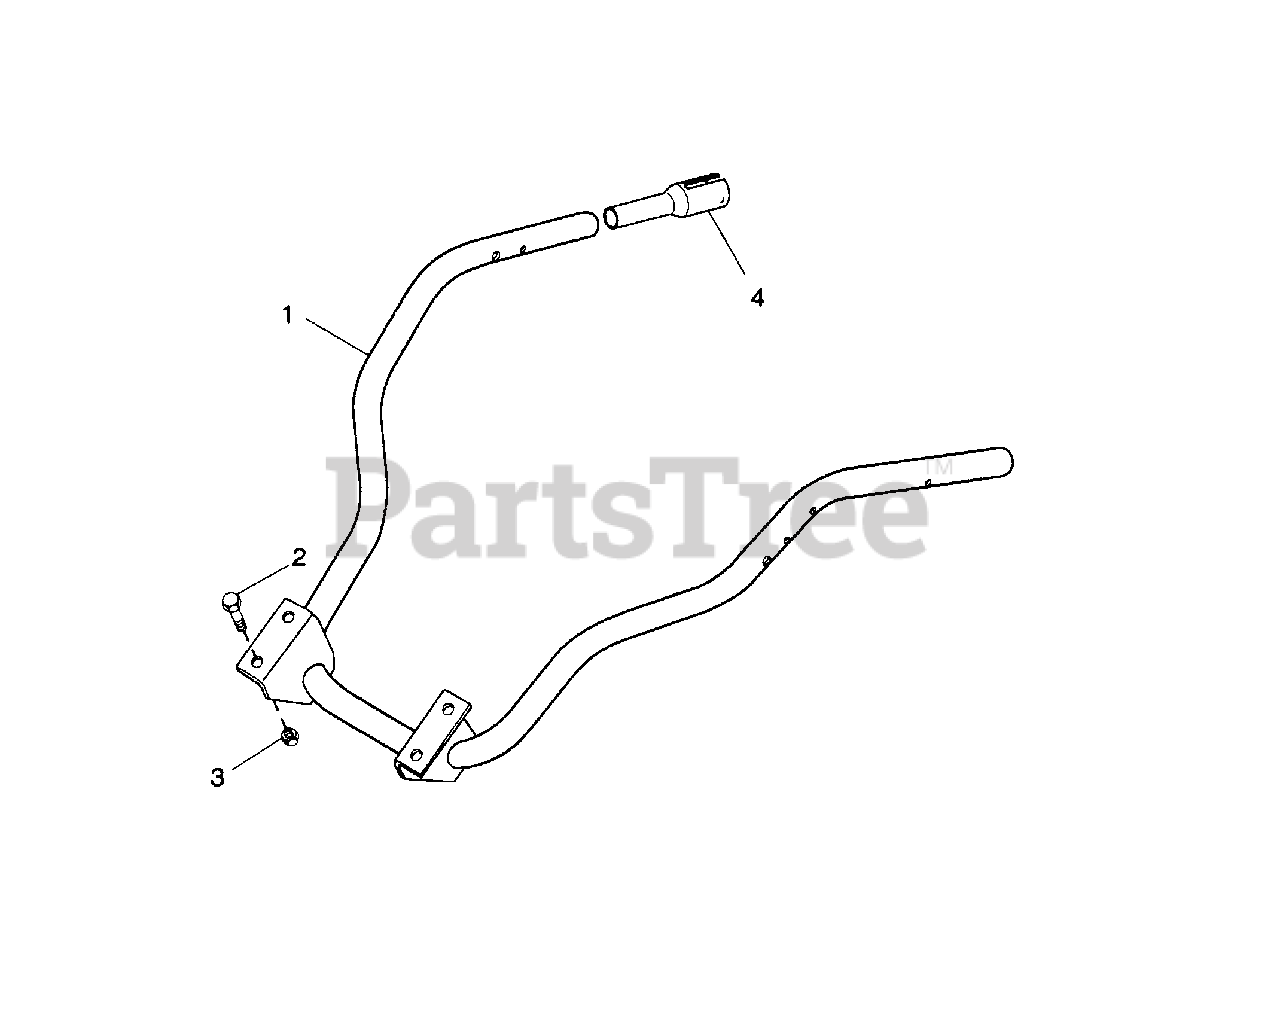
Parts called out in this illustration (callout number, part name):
1	WLDMT, HANDLEBAR
2	BLT-HEX .38-16 X 1.25 PL GR 8
3	NUT-LK-NYL .375-16 PL
4	INSERT, HANDLEBAR(2-WHEEL)
